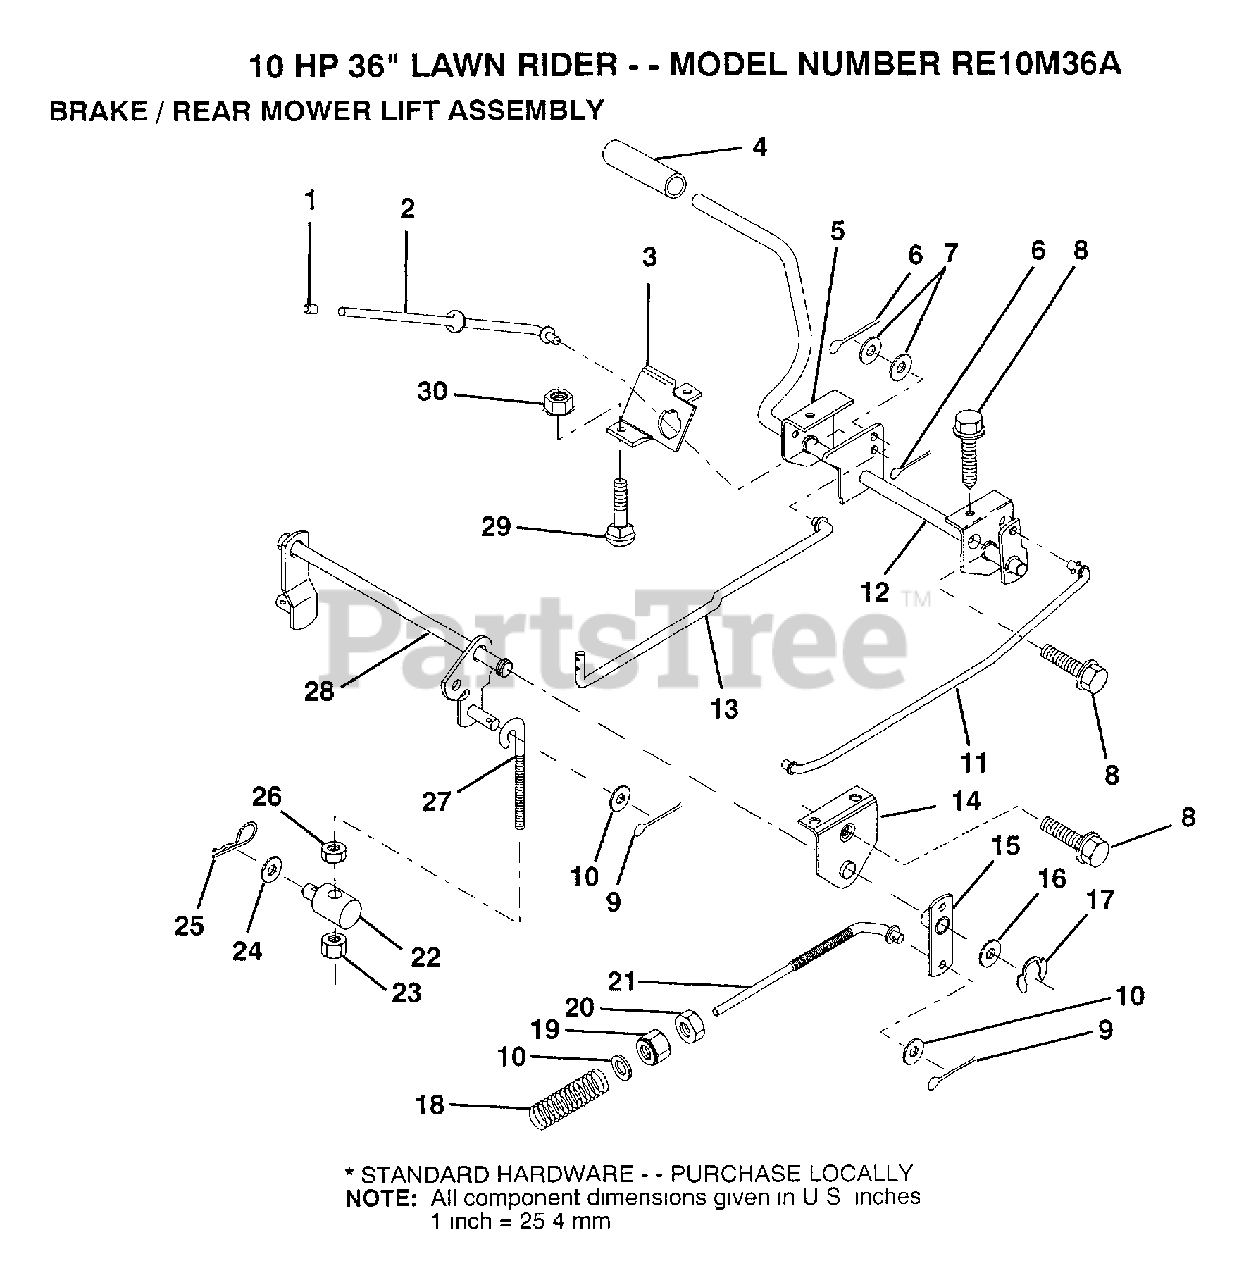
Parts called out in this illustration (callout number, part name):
1	PLUNGER CAP T
2	"ROD,PARK BRAKE"
3	BRKT PARKING BRAKE
4	FOOT PEDAL COVER
5	BRK ASM CLUT LH
7	WASHER
8	SCREW LT
9	COTTER PIN
10	WASHER
13	"ROD,CLUTCH"
14	"BRKT,LIFT SHAFT"
15	PVT BRAKE ARM ASM
16	WASHER T
17	KLIP RING
18	SPRING ROD LT
19	NUT
20	NUT
24	WASHER
25	SPRING.RETAINER
26	LOCKNUT
27	"LINK, MOWER REAR"
